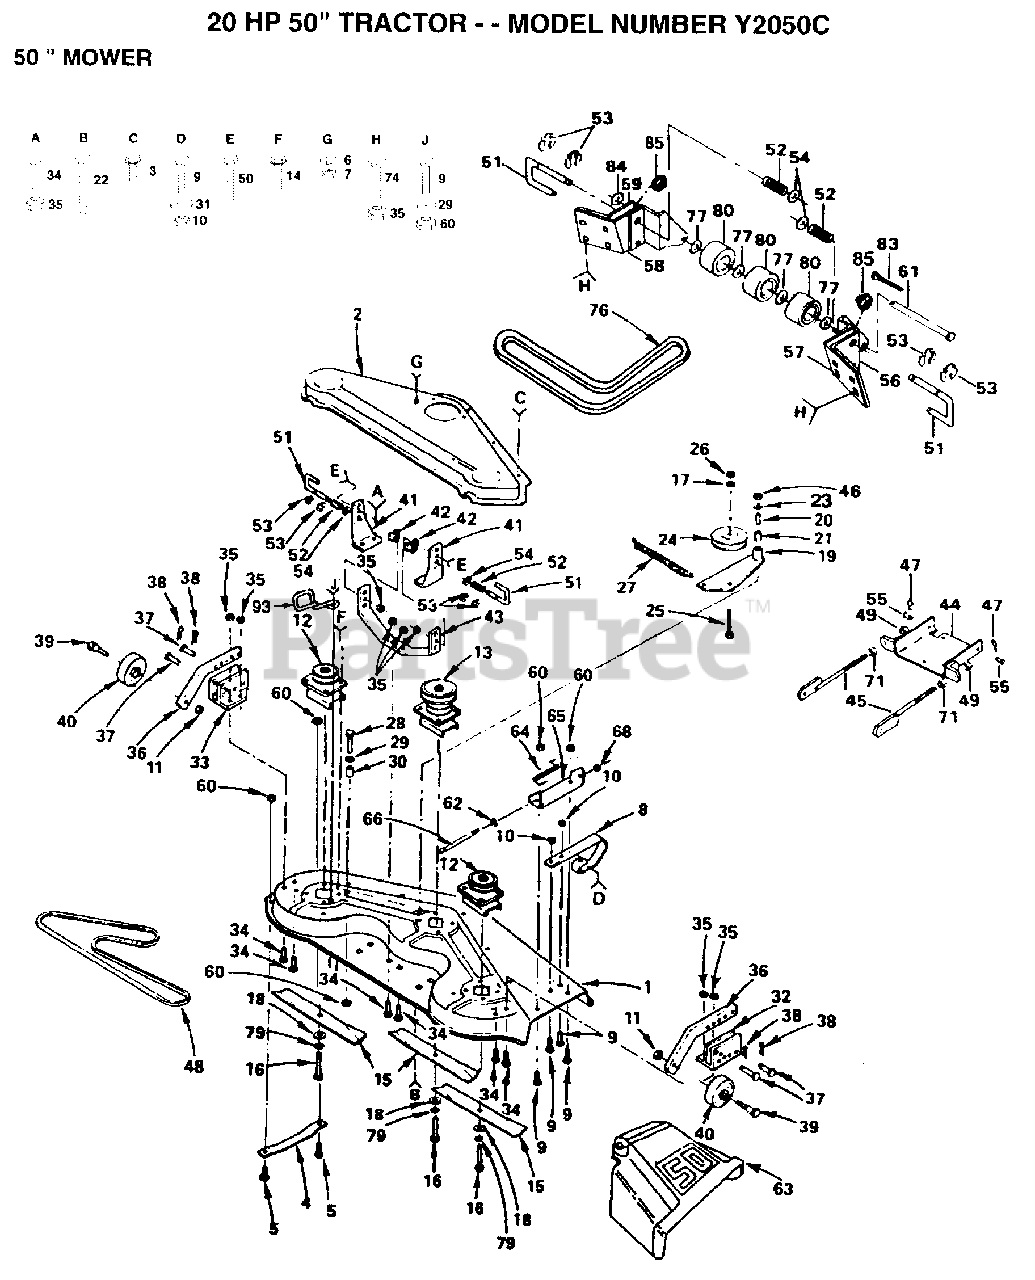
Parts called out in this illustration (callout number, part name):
2	CVR DRIVE DECK
3	SCREW LT
4	RUNNER-LH M
5	BOLT
6	LOCKWASHER
7	NUT.HEX.5/16-18
9	BOLT
11	LOCKNUT
14	SCREW
15	"BLADE.50""STD.LIFT"
16	BOLT.3/8-24X1-1/2
17	LOCKWASHER
18	WASHER
19	ARM ASSY GT
22	BOLT
23	WASHER
24	IDLER-FLAT T
26	NUT.HEX.3/8-16UNC
27	SPRING T
28	BOLT
29	WASHER M
30	SPACER SPLIT LT
31	WASHER
32	GUAGE WHL BRKT GT
33	GUAGE WHL BRKT GT
34	BOLT
36	GUAGE WHL BAR GT
37	PIN.CLEVIS
39	BOLT.SHOULDER
40	WHEEL GAGE DONUT
41	SUSP BRKT GT
42	SPACER GT
43	SUSP BRACE GT
45	BRACKET.SUSPEN.AS
46	JAM NUT TI
47	RETAINER.SPRING
48	V-BELT M
49	NUT LTV
50	BOLT
51	RELEASE PIN GT
52	SPRING M
53	KLIP RING
55	CLEVIS PIN GT
56	BRACKET T
57	BRACKET T
58	BRACKET T
59	BRACKET T
61	PIVOT PIN T
62	WASHER
63	DEFLECTOR
64	SPRING TORSION
65	BRKT DEFLECTOR
66	ROD-HINGE T
68	NUT PUSH M
71	NUT
74	BOLT
76	BELT-V.93.5.MWR
77	WASHER T
80	ROLLER T
83	COTTER PIN
85	SPACER T
93	BELT RETIANER
